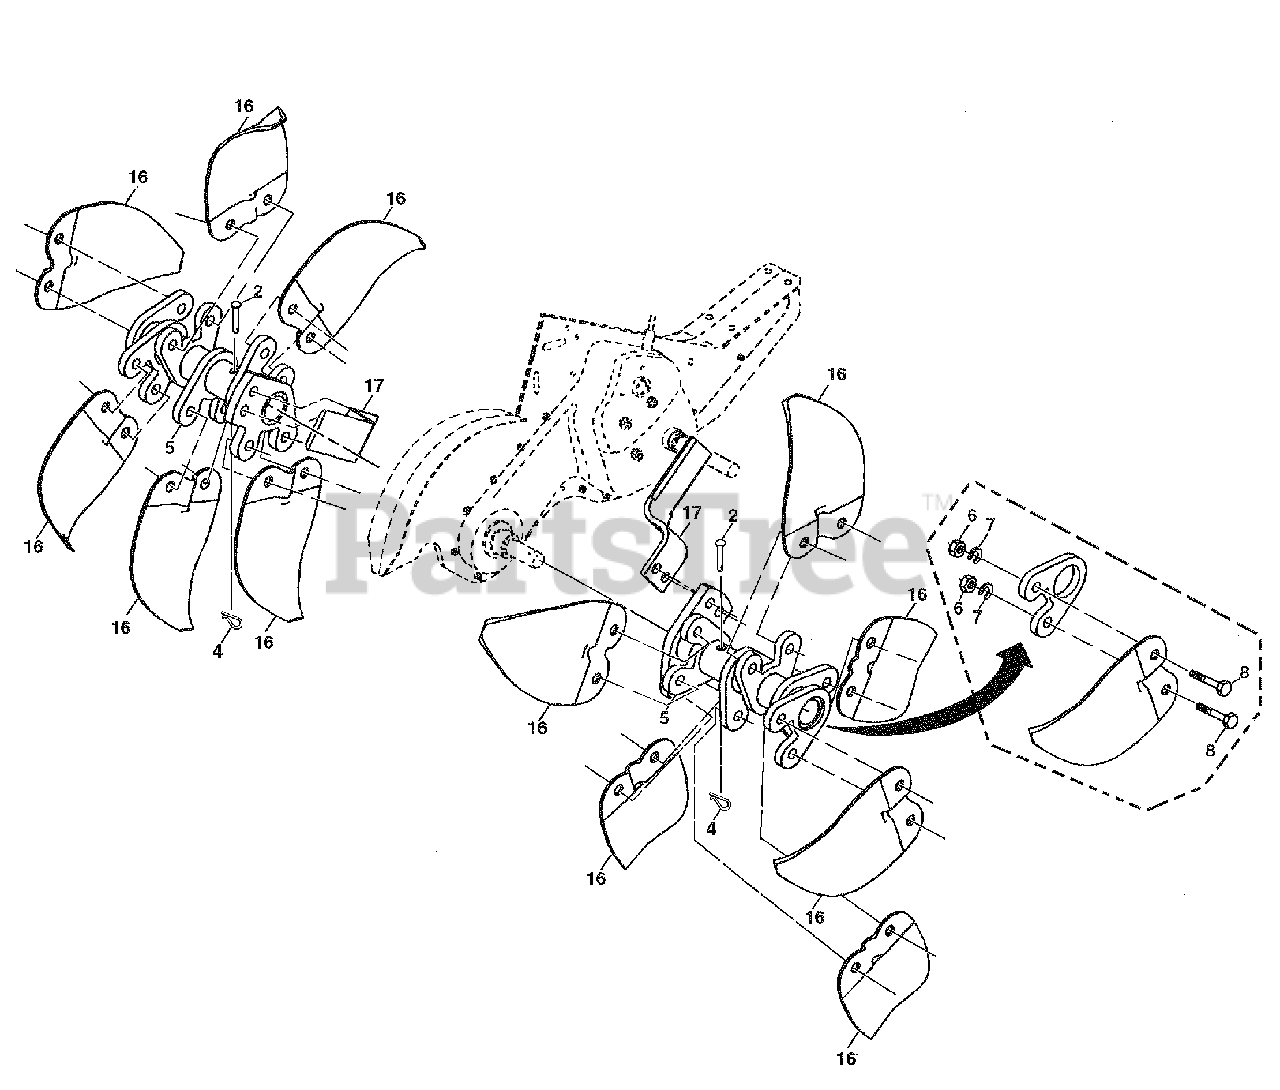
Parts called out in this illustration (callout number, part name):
2	Pin, Shear
4	Clip, Hairpin
5	Hub Assembly
6	Nut, Hex 3/8-24
7	Washer, Lock 3/8
8	Bolt, Hex 3/8-24 x 1
16	Tine, Spade
17	Tine, Cleaning
